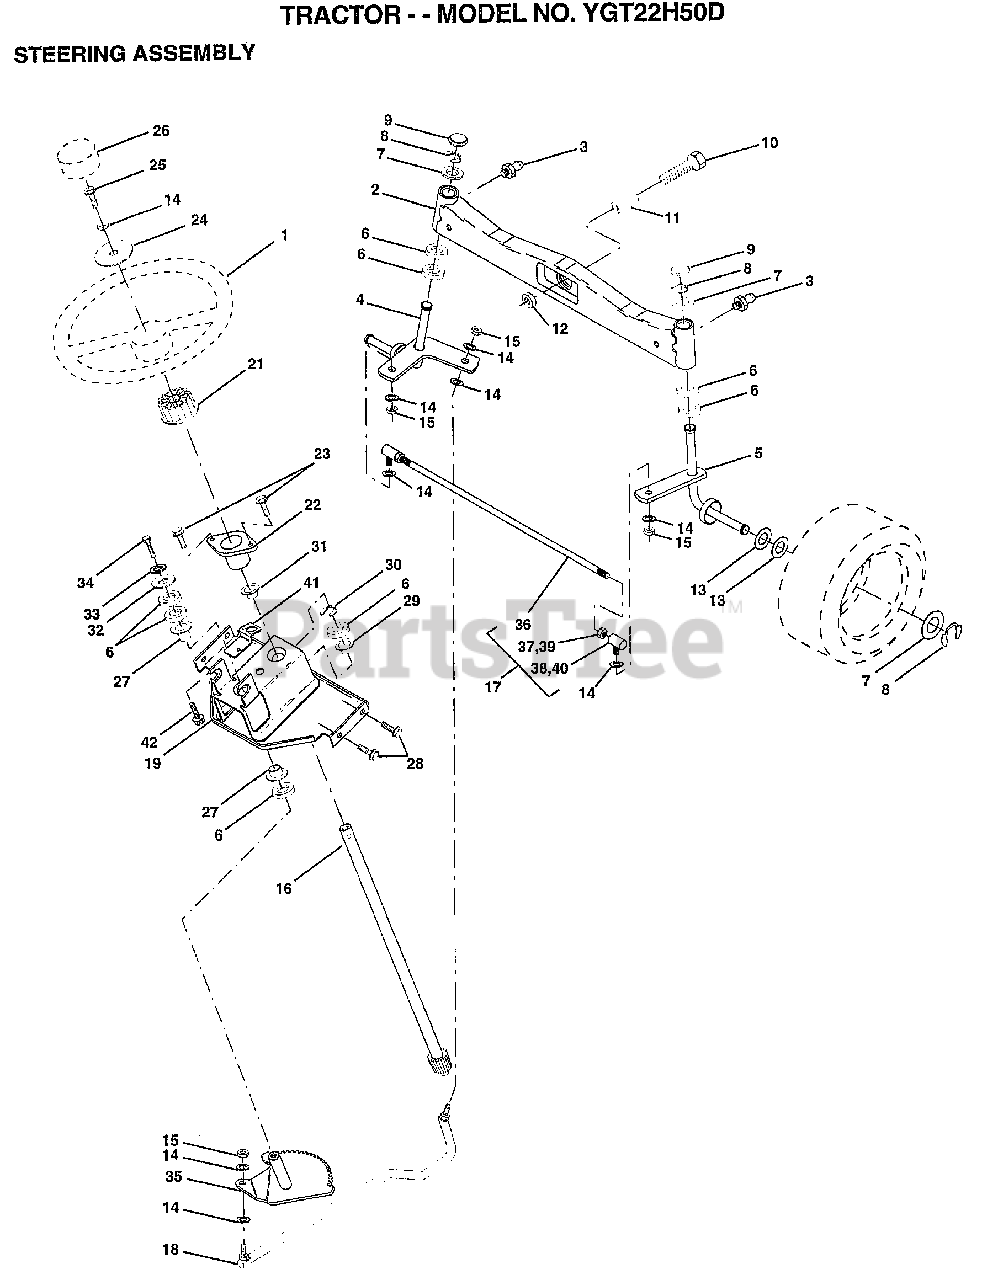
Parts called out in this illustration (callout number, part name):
3	ZERK M
4	SPINDLE ASM LH
5	SPINDLE ASM RH
6	WASHER .T
7	WASHER
8	RING
9	CAP
10	BOLT
11	SPACER BEARING
12	"NUT-LOC,FLANGE LT"
13	WASHER
14	LOCKWASHER
15	GRIPCO NUT
16	SHAFT.STEER.VGT
17	ROD.ASM.TIE.BALL
18	DRAGLINK.BALL.JOI
19	SUPPORT ASM-STEER
21	ADAPTER LT
22	"BUSHING,STEERING"
23	"SCREW-TT,10-32 FL"
24	WASHER T
25	BOLT
26	"INSERT,STR WHEEL"
27	COL. SRTG. BEAR.
28	SCREW
29	"FLANGE GT, BEAR."
30	KLIP RING
31	BUSHING.NYLINER.
32	WASHER
33	LOCKWASHER
34	BOLT
35	GEAR.ASM.SECTOR.
37	NUT
38	JOINT.RH
39	NUT
40	JOINT.LH
41	"BRKT-SW, INTER"
42	SCREW LT
